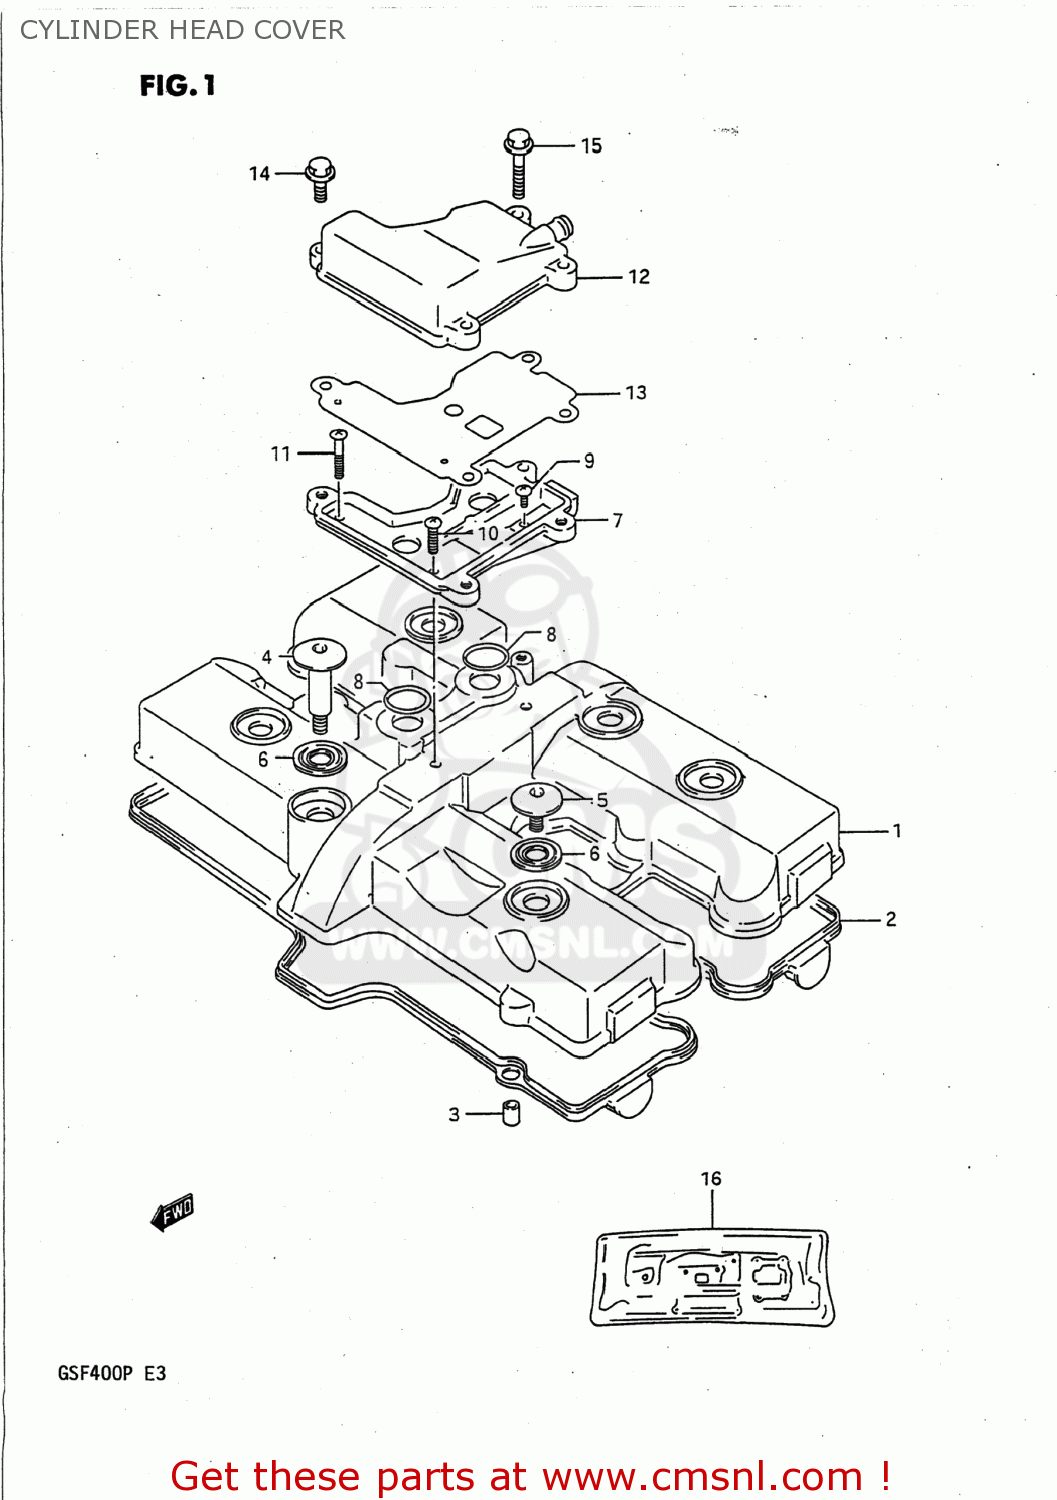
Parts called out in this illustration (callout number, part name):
1	COVER,CYLINDER HEAD
2	GASKET,CYLINDER HEAD COVER (NAS)
3	PIN(6.2X8X11)
4	BOLT(7X37)
5	BOLT(7X18.5)
6	WASHER(10.6X25.5X2.3)
7	COVER,BREATHER,LOWER
8	O RING(D:2.4,ID:19)
9	SCREW 5X10
10	SCREW
11	SCREW
12	COVER,BREATHER,UPPER
13	GASKET,BREATHER COVER (NAS)
14	BOLT 6X20
15	BOLT 6X35
16	GASKET SET (NAS)
